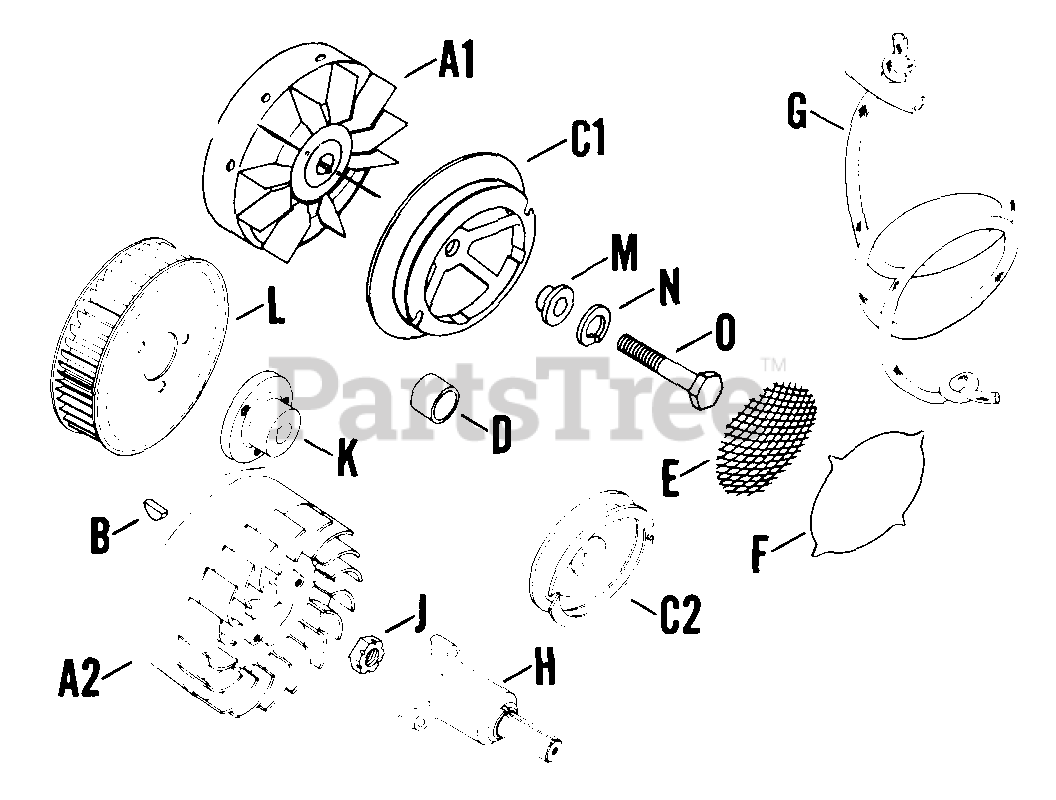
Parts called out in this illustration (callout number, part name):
A1	FLYWHEEL - DISCONTINUED
B	KEY - DISCONTINUED
C1	PULLEY - USE C-220150
E	SCREEN, GRASS - DISCONTINUED
F	RETAINER
G	ROPE - USE A-230099-S
J	NUT - DISCONTINUED
